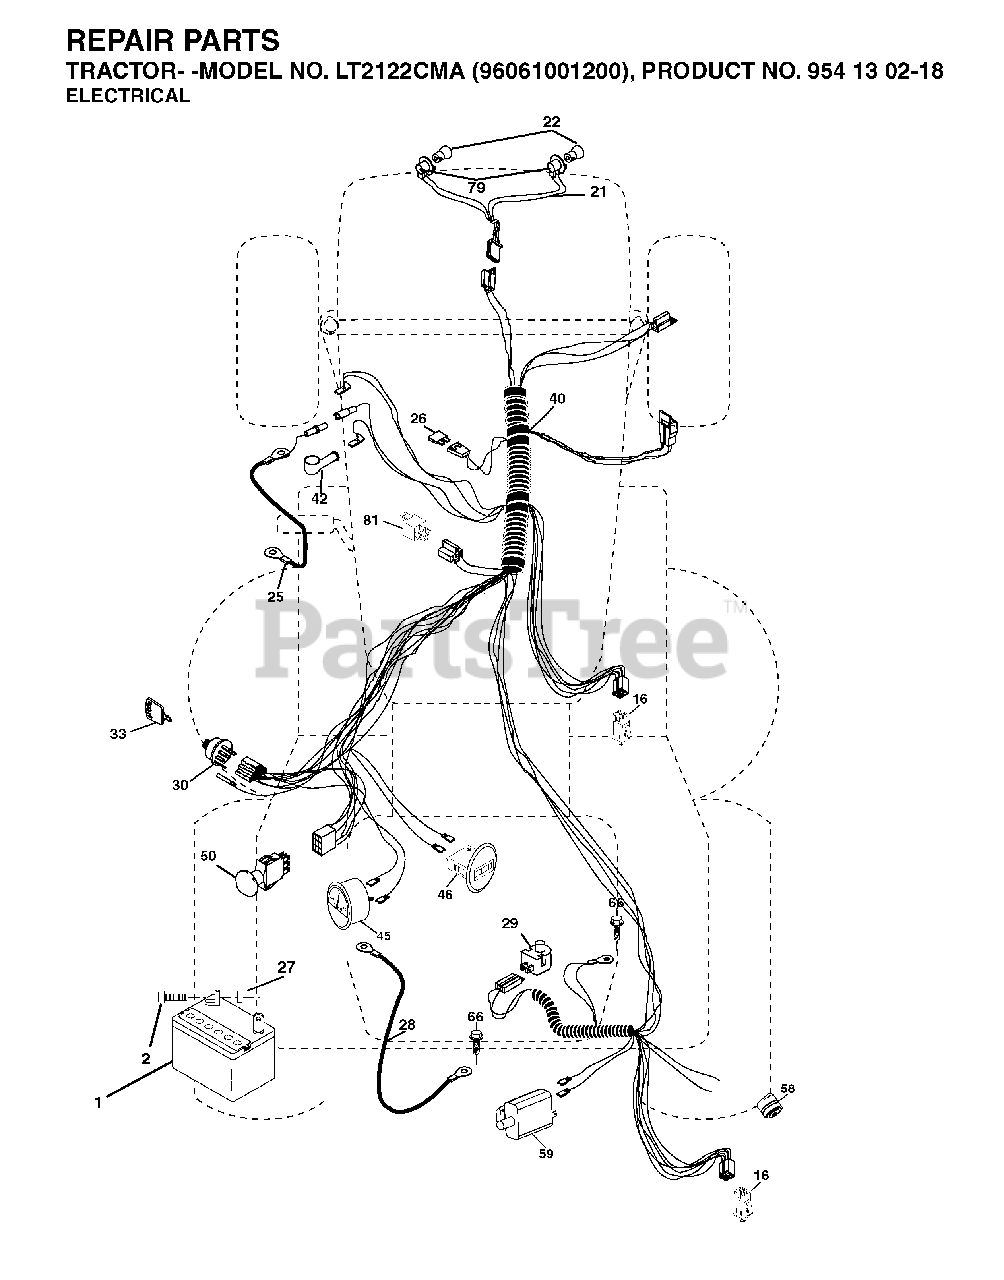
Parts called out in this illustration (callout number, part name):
1	BATTERY 12V .35 AMP
16	SWITCH INTERLOOK PUSH-IN
21	HARNESS.W/LIGHT SOCKET
22	LIGHTBULB
26	FUSE 20AMP
27	NUT
28	CABLE GROUND
29	SWITCH SEAT
30	IGNITION SWITCH
33	KEY MLD GEN DELTA
42	COVER.TERMINAL.RED
46	HOURMETER SNAP-IN
50	PTO SWITCH
58	BUZZER
66	SCREW LT
79	BULB HOLDER ASM.
81	RELAY.ASSY.T
